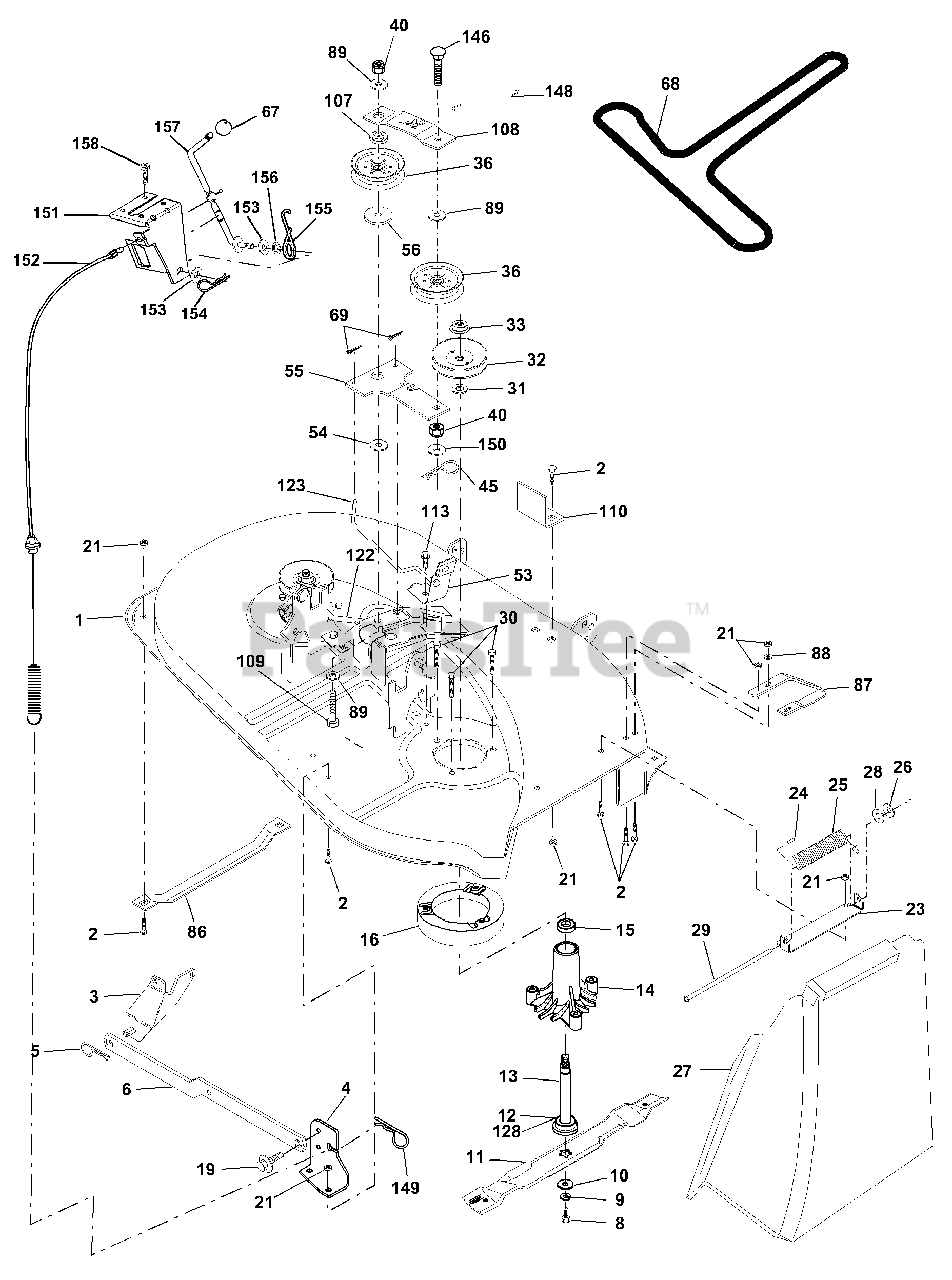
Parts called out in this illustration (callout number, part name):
1	Mower Housing Assembly
2	Bolt Carriage 5/16-18 x 3/4
3	Bracket Asm Fr. Sway Bar
4	Bracket Deck Sway Bar 38"/42"
5	Retainer Spring
6	Arm, Suspension, Rear
8	Bolt 3/8-24 x 1.25 Grade 8
9	Washer, Lock 3/8
10	Washer, Hardened
11	Blade Mower
12	Bearing, Ball
13	Shaft Assembly, Mandrel, Vented
14	Housing, Mandrel, Vented
15	Bearing, Ball, Mandrel
16	Stripper, Vented Mower Deck
19	Bolt, Shoulder
21	Nut
23	Bracket, Mower Deflector
24	Cap, Sleeve
25	Spring, Torsion, Deflector
26	Nut, Push
27	Shield, Deflector
28	Washer 11/32 x 5/8 x 16 Gauge
29	Rod, Hinge
30	Screw Thdrol. Washer Head
31	Washer, Spacer
32	Pulley, Mandrel
33	Nut, Toplock 9/16
36	Pulley, Idler, Flat
45	Retainer
53	Brake Assembly
54	Washer, Hardened
55	Idler Arm Assembly
56	Spacer, Retainer
67	Knob
68	V-Belt, 42" Mower
69	Pin, Cotter 3/32 x 3/4
86	Runner, LH
87	Runner, RH
88	Washer 11/32 x 3/4 x 16 Ga
89	Washer 13/32 x 1 x 12 Ga.
107	Spacer Retainer
108	Stiffener, Idler Arm
109	Bolt, Hex Hd 3/8-16 x 2-1/2
110	Upstop Deck Front 38"
113	Screw 5/16-1/ x 3/4
122	Rod, Brake LH
123	Rod, Brake RH
128	Washer Felt
146	Bolt Carriage Idler
148	Spring Return Idler
149	Retainer Spring Yellow
150	Washer 9/32 x 3/4 x 16 Ga.
151	Bracket Clutch Cable
152	Clutch Cable 38"/46"
153	Washer Flat 3/8" Type B
154	Spring Retainer
155	Spring Retention LVR CLTCH CAB
156	Spacer Clutch Cable
157	Rod Clutch Cable 3/8"
158	Screw Hex Thd Cut 1/4-20 x 5/8
